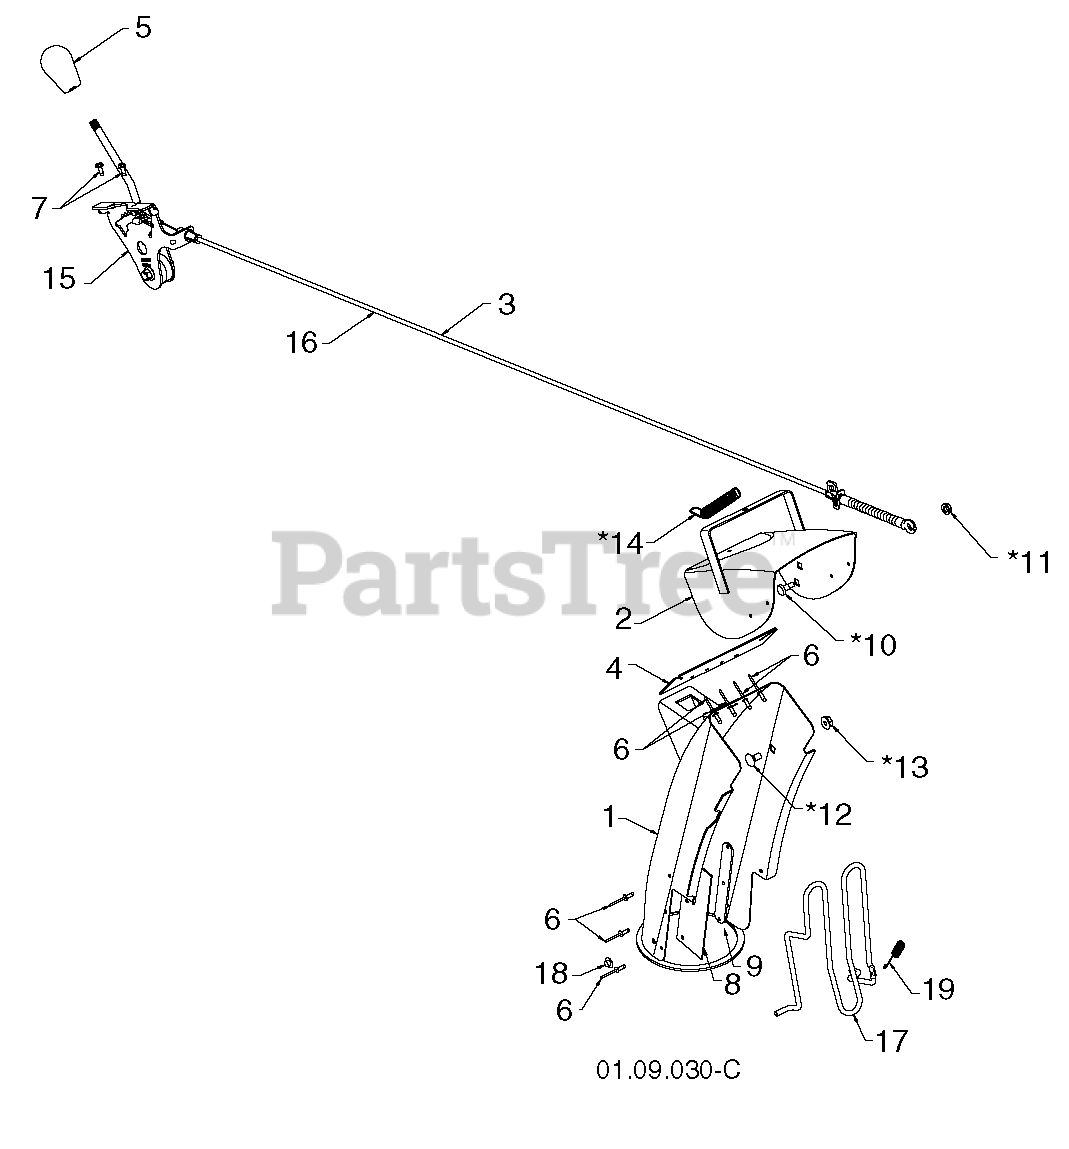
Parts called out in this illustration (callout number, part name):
1	RP_CHUTE.WELDMENT.SNOW.ORANGE
2	DEFLECTOR.WELDMENT.PNT.ORANGE
3	RP CRTL.ASM.DEFLECTOR.BLACK.SN
4	SEAL.DEFLECTOR
5	KNOB.OVERMOLD.DS.HUSQVARNA/BLK
6	RIVET BLIND
8	SHIELD.SNOW.CHUTE
9	STRAP.SHEILD.RETAINER
10	BOLT, SHOULDER
11	NUT.HEX.FLANGE.1/4
12	BOLT
13	NUT.LOCK.5/16-18
14	SPRING.DEFLECTOR.REM.CHUTE
15	RP CNTRL.HEAD.ASSEM.DEFLECTOR
16	CABLE.DEFLECTOR.SNOW
17	ROD.GUARD.CHUTE (2 2)
18	NUT
19	SPRING.CHUTE.GUARD
